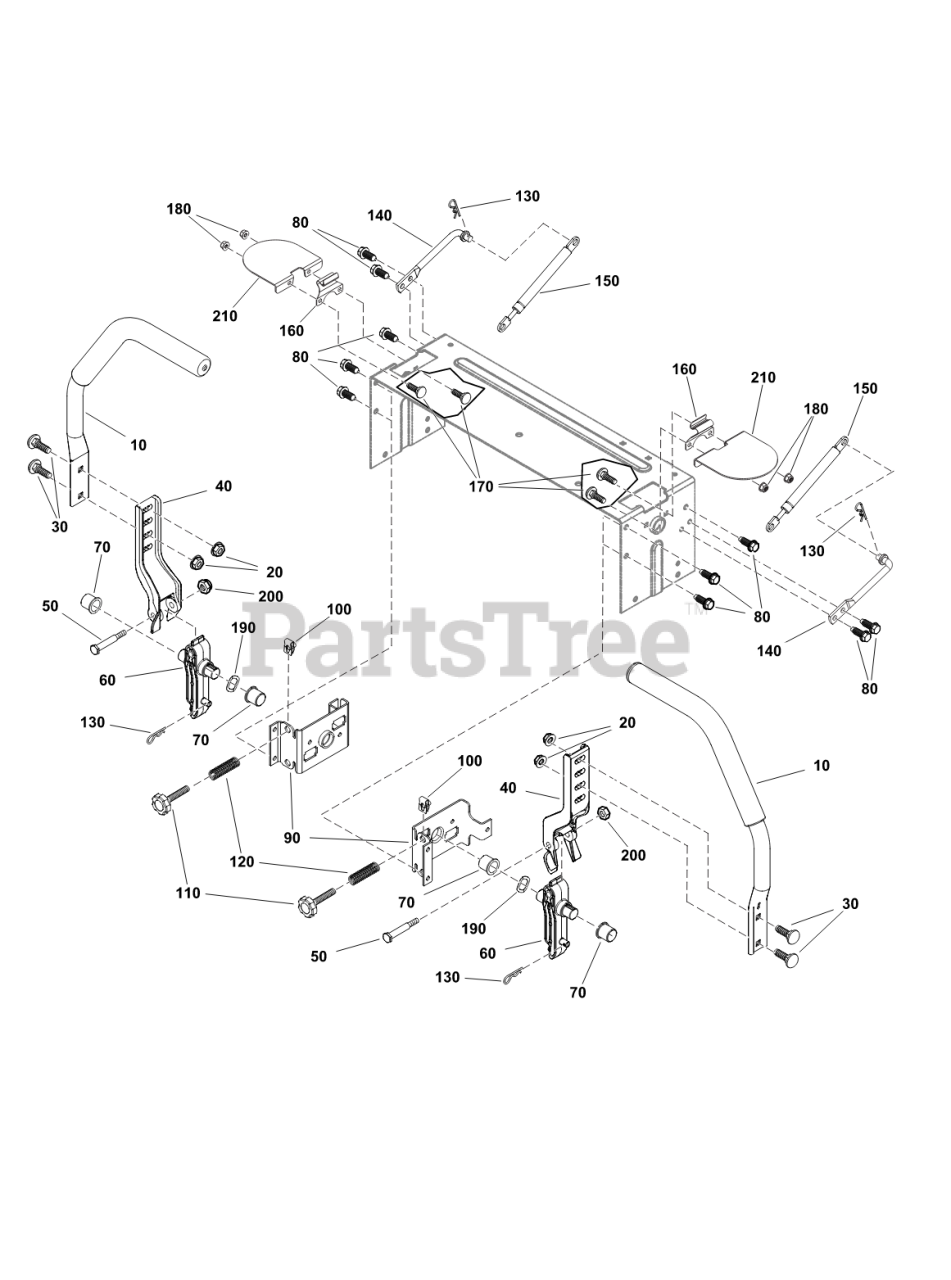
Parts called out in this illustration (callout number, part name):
10	HANDLE, CONTROL
30	BOLT, 5/16-18 X 1", C
40	ARM, UPPER CONTROL
50	BOLT,SHLDR,5/16-18
60	ARM, LOWER CONTROL
70	BUSHING-0.765IDX
80	SCREW, 5/16-18.625
90	PIVOT, Inner Control
100	BODY CLIP, 5/16-18 X
110	KNOB, 5/16-18 X 2.5
120	SPRING-COMP 0.50 IDX
130	PIN, HAIR, .0585" X 1
140	ROD, DAMPNER MNT
150	DAMPENER
160	LATCH, CONTROL ARM
170	BOLT,1/4-20X.75
190	WSHR, 3 WAVE, .750
